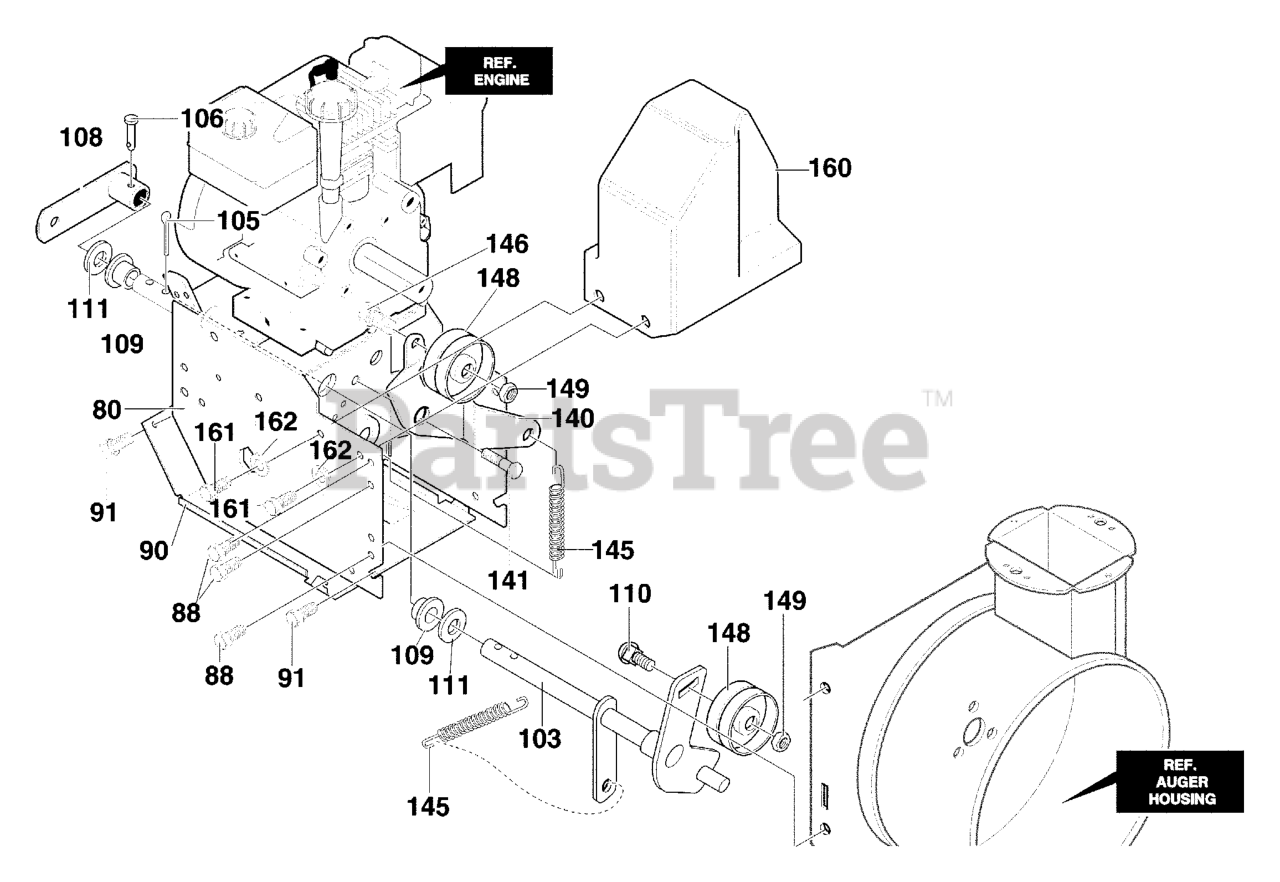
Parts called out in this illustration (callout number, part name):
80	FRAME, ASSY
88	SCREW, 5/16-18 x 0.50
90	COVER, BOTTOM
91	SCREW, 1/4-20X.63 WAHHTAP
103	ASSY., IDLER
105	HAIR PIN
106	CLIP, KLIK
108	ASSY.,SPRING ATTACH WHEEL
109	BEARING, FLANGE
110	BOLT 3/8-16X1.25
111	FLATWASHER
140	LEVER, IDLER ARM TRACTION
141	BOLT, 5/16-18
145	SPRING, IDLER TRACTION DR
146	SCREW, 3/8-16 x 1.25
148	PULLEY, IDLER
149	NUT, 3/8-16 CTRLKJAM
160	BELT COVER
161	SCREW, 1/4-20X.63 WAHHTAP
162	FLATWASHER, .281X.63X.065
